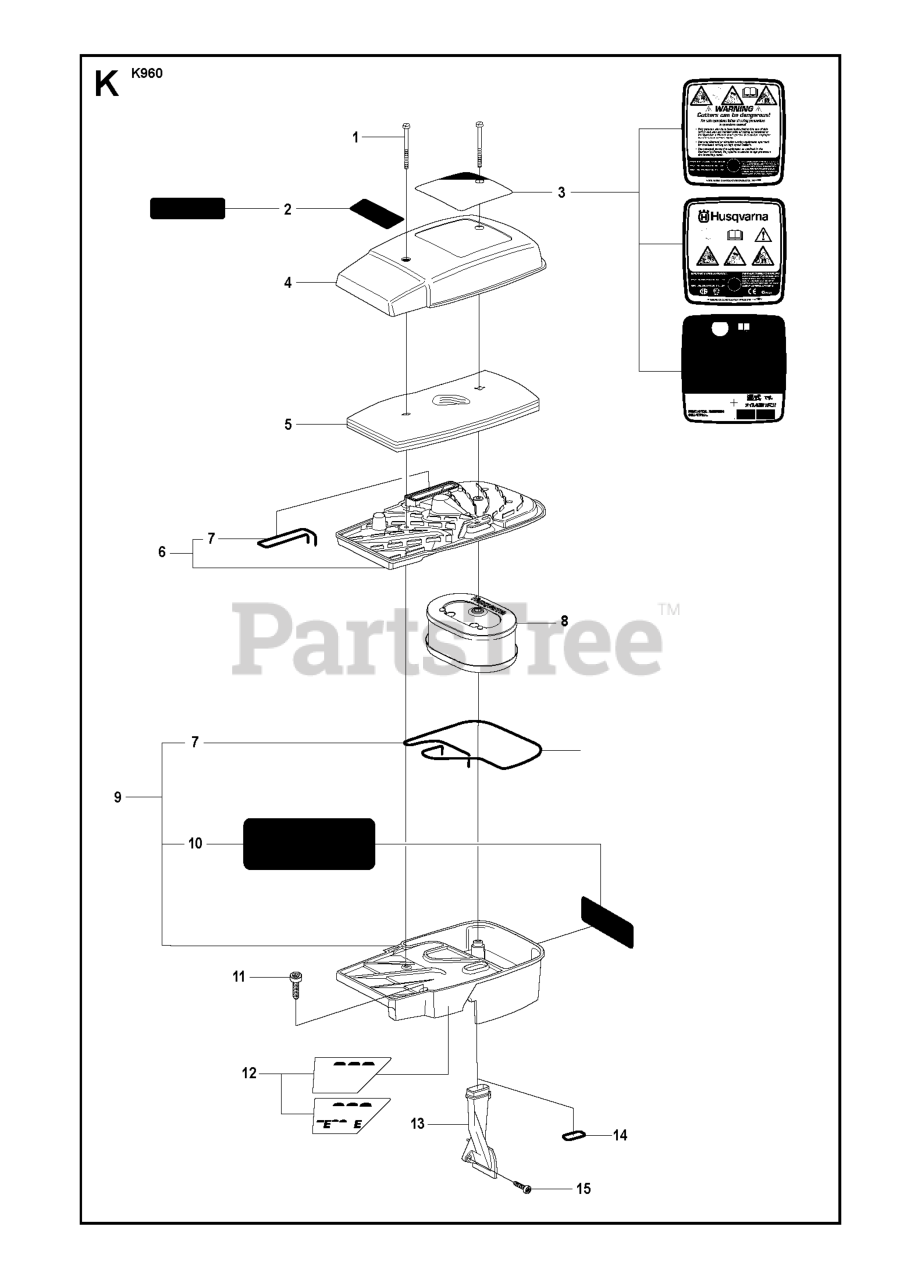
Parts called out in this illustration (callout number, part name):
1	SCREW
2	LABEL DECOMP. LEFT
3	LABEL EPA2 USA
4	AIR FILTER COVER
6	FILTER BOTTOM
8	AIR FILTER
9	CYLINDER COVER ASSY
12	LABEL CYL COVER K960 RESCU
12	LABEL CYL COVER K960 HVA
